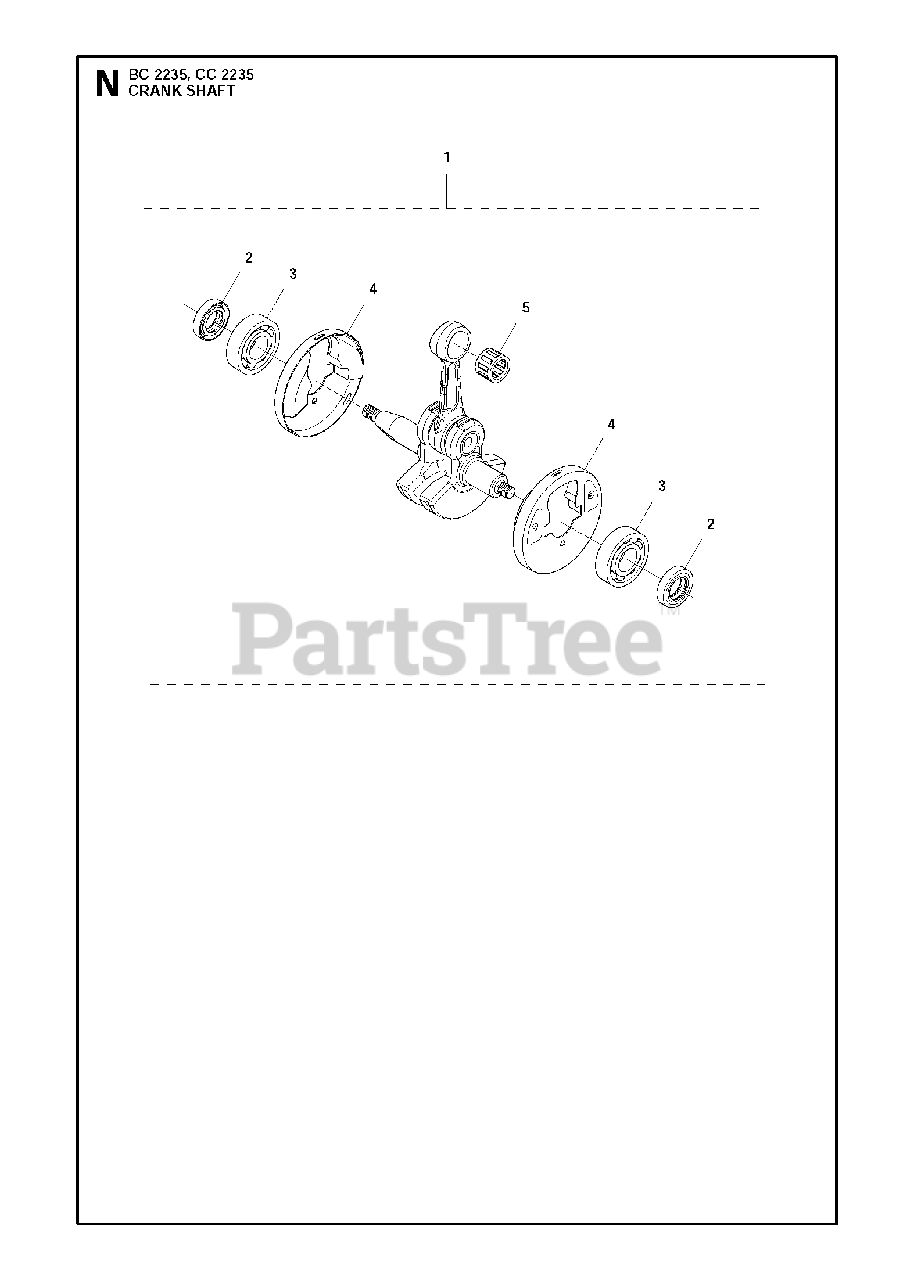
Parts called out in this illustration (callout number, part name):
1	CRANKSHAFT
2	SEALING RING
3	BALL BEARING
4	COLLAR
5	SUPPORT BUSHING
